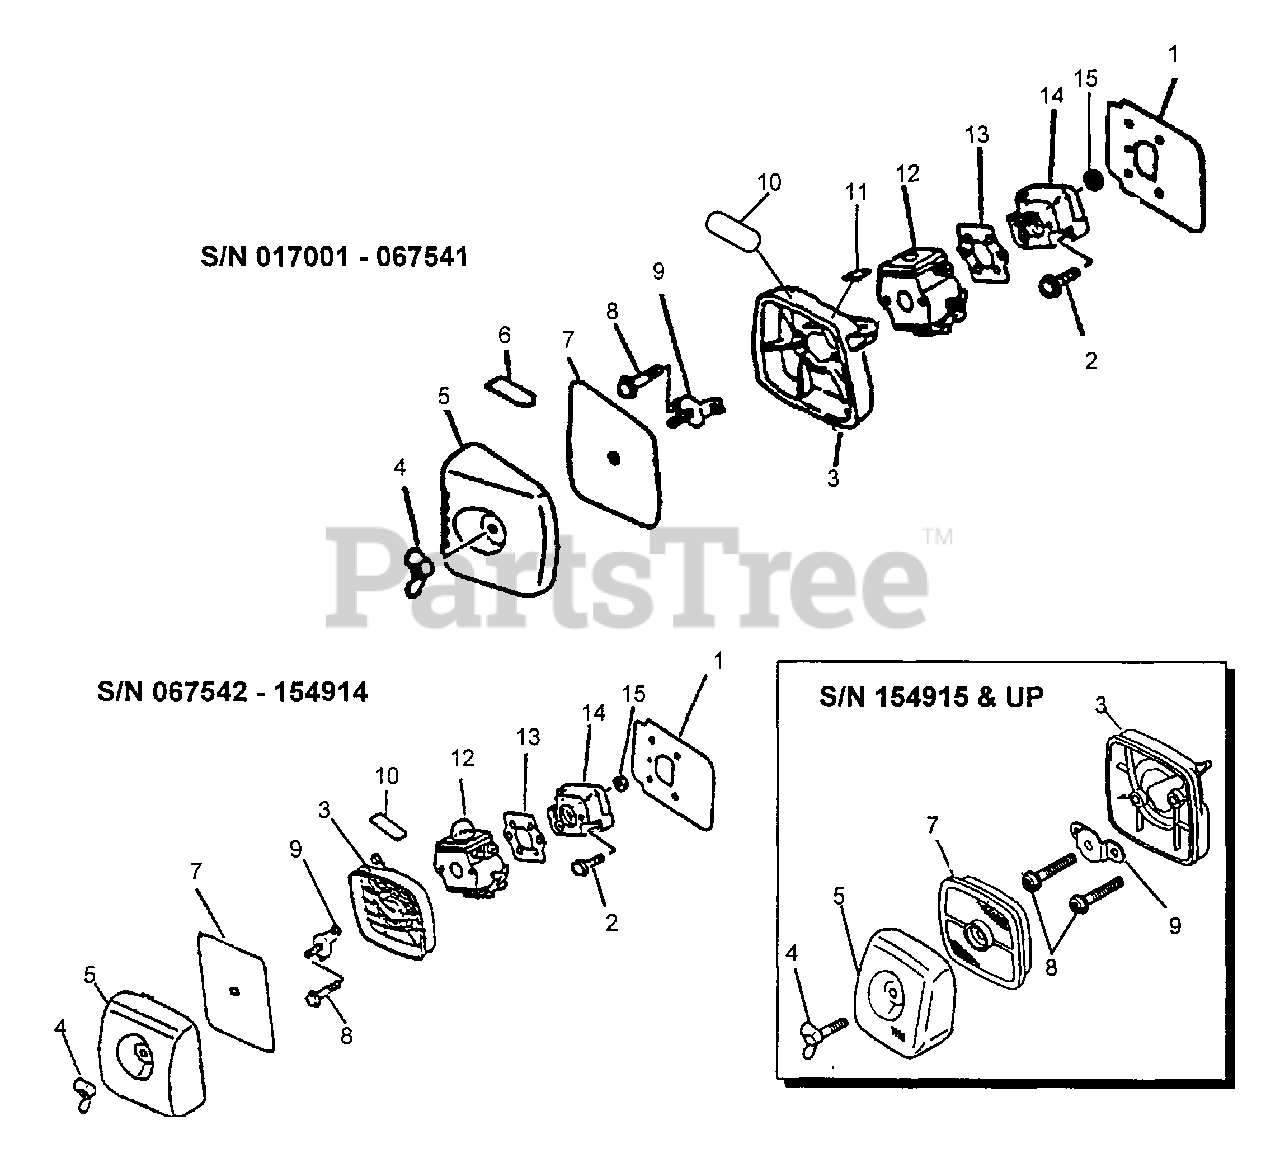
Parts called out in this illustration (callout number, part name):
1	SHIELD, INTAKE
2	SCREW - 5X20
3	AIR FILTER CASE ASSY
4	WINGNUT - 6
4	THUMBSCREW
5	COVER, AIR FILTER
5	COVER, AIR FILTER - BLACK
5	COVER, AIR FILTER - GRAY
6	LABEL - TOP
7	FILTER, AIR
7	FILTER, AIR - SINGLE LAYER
8	SCREW - 5X64
8	SCREW - 5X65
9	PLATE, PREVENT
10	LABEL - CHOKE
11	LABEL - IDLE
12	CARBURETOR C1U-K10A
12	CARBURETOR C1U-K17
12	CARBURETOR C1U-K27B
12	CARBURETOR C1U-K45
13	GASKET, INTAKE
14	INSULATOR, INTAKE
